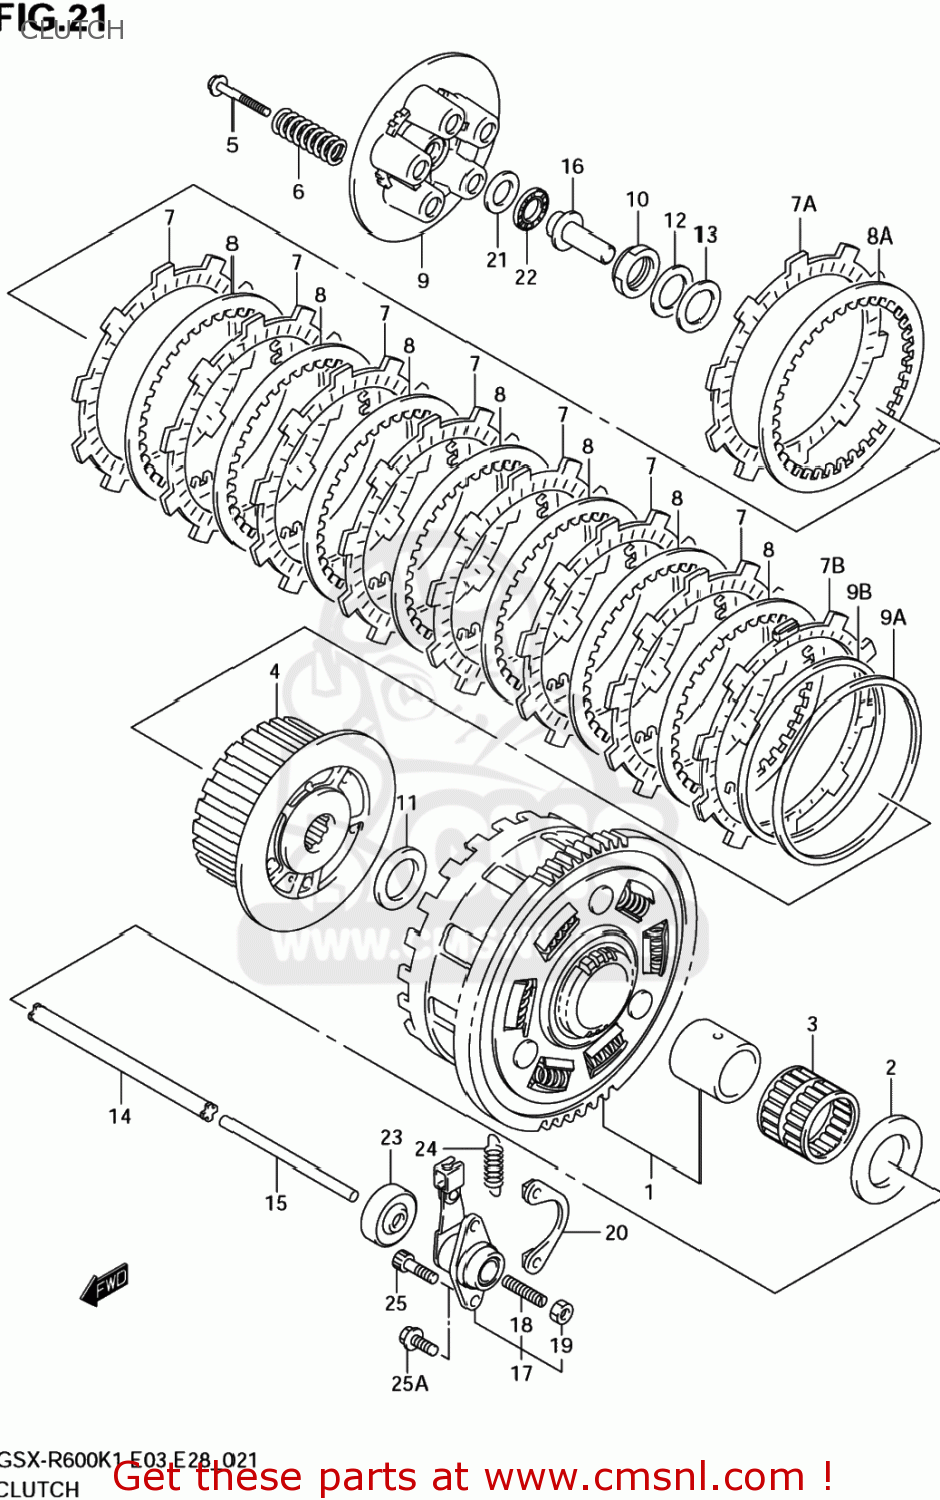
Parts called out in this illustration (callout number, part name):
1	GEAR ASSY,PRIM
2	WASHER(25X54X2.4)
3	BEARING(35X40X29.8)
4	HUB,CLUTCH SLEEVE
5	BOLT,CLUTCH SPRING
6	SPRING,CLUTCH
7	PLATE,CLUTCH DRIVE NO.1 (NAS)
7A	PLATE,CLUTCH DRIVE (NAS)
7B	PLATE,CLUTCH DRIVE NO.3 (NAS)
8	PLATE,CLUTCH DRIVEN NO.2 (NAS)
8A	PLATE,CLUTCH DRIVEN NO.1 (NAS)
9	DISC,CLUTCH PRESSURE
9A	SEAT,CLUTCH PLATE WAVE WASHER
9B	WASHER,CLUTCH PLATE
10	NUT
11	WASHER(25X50X2.5)
12	WASHER
13	SHIM(25X38X1)
14	ROD,CLUTCH
15	ROD,CLUTCH PUSH,L
16	PIECE,CLUTCH PUSH
17	SCREW ASSY,CLUTCH RELEASE
18	SCREW(6X25)
19	NUT
20	NUT,CLUTCH RLSE SCREW
21	WASHER(15.5X28X1)
22	BEARING(15X28X2)
23	SEAL,OIL(6X34X10)
24	SPRING
25	BOLT
25A	BOLT
